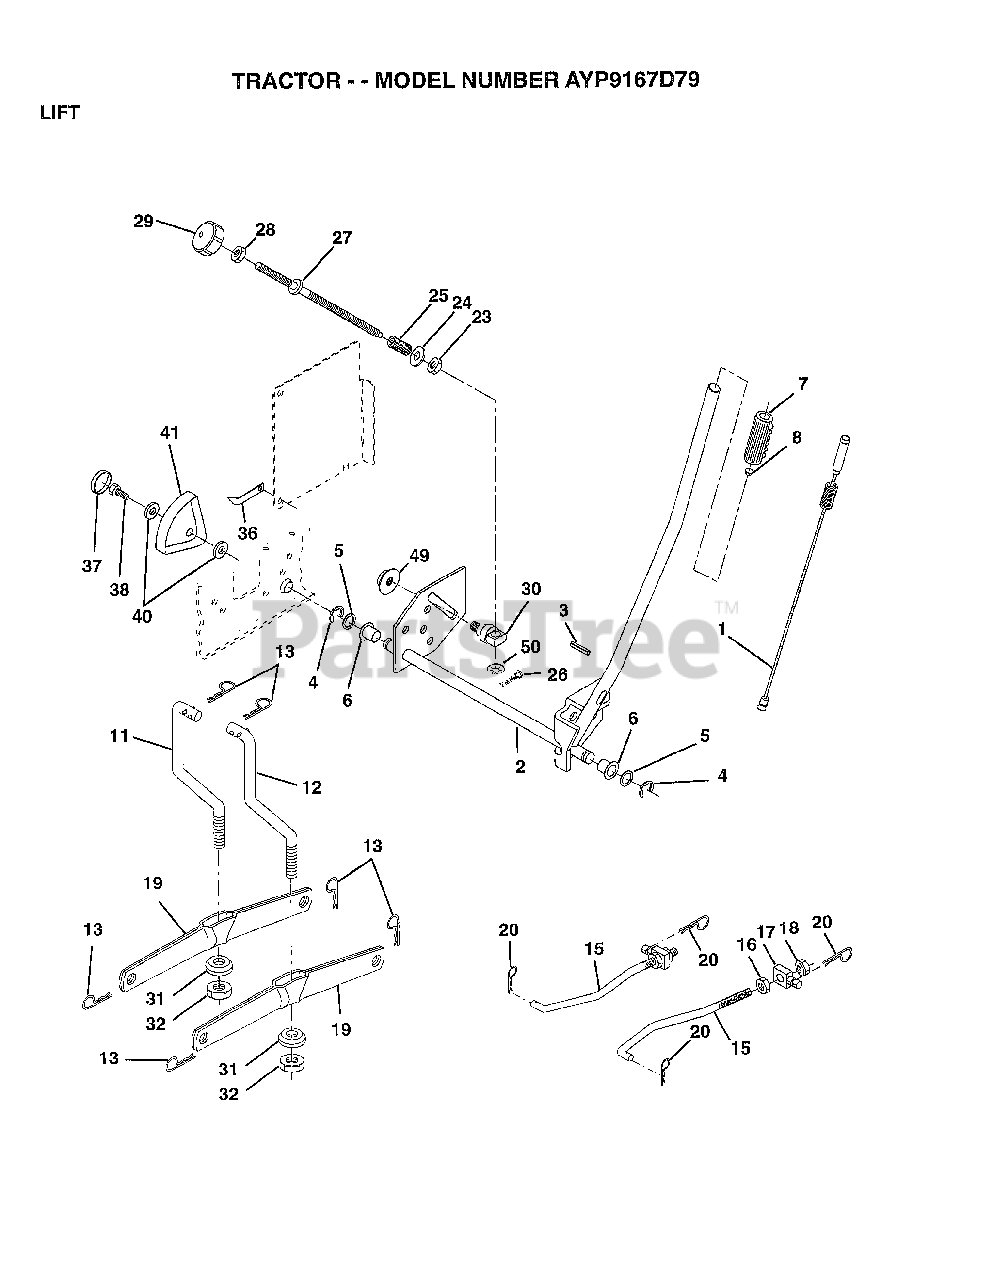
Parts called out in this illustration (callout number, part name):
1	WIRE ASM W.SPRING
2	"SHAFT ASM LIFT,RH"
3	PIN-GROOVE LT
5	WASHER
6	NYLON BEARING
7	GRIP HANDLE
15	LINK.FRONT
16	NUT
17	TRUNION
18	NUT.LK.W/WSH.1/2.
19	ARM SUSP REAR
20	RETAINER.SPRING
23	NUT T
24	WASHER
25	SPRING T
28	NUT
29	KNOB INF 3/8-16
30	TRUNNION
31	BEARING PVT LH
32	NUT.CROWNLOCK.3/8
36	POINTER-INDICAT
37	"PLUG,HOLE"
38	SCREW
40	WASHER
41	HEIGHT INDICATOR
49	NUT.HXFLG.LOCK.
